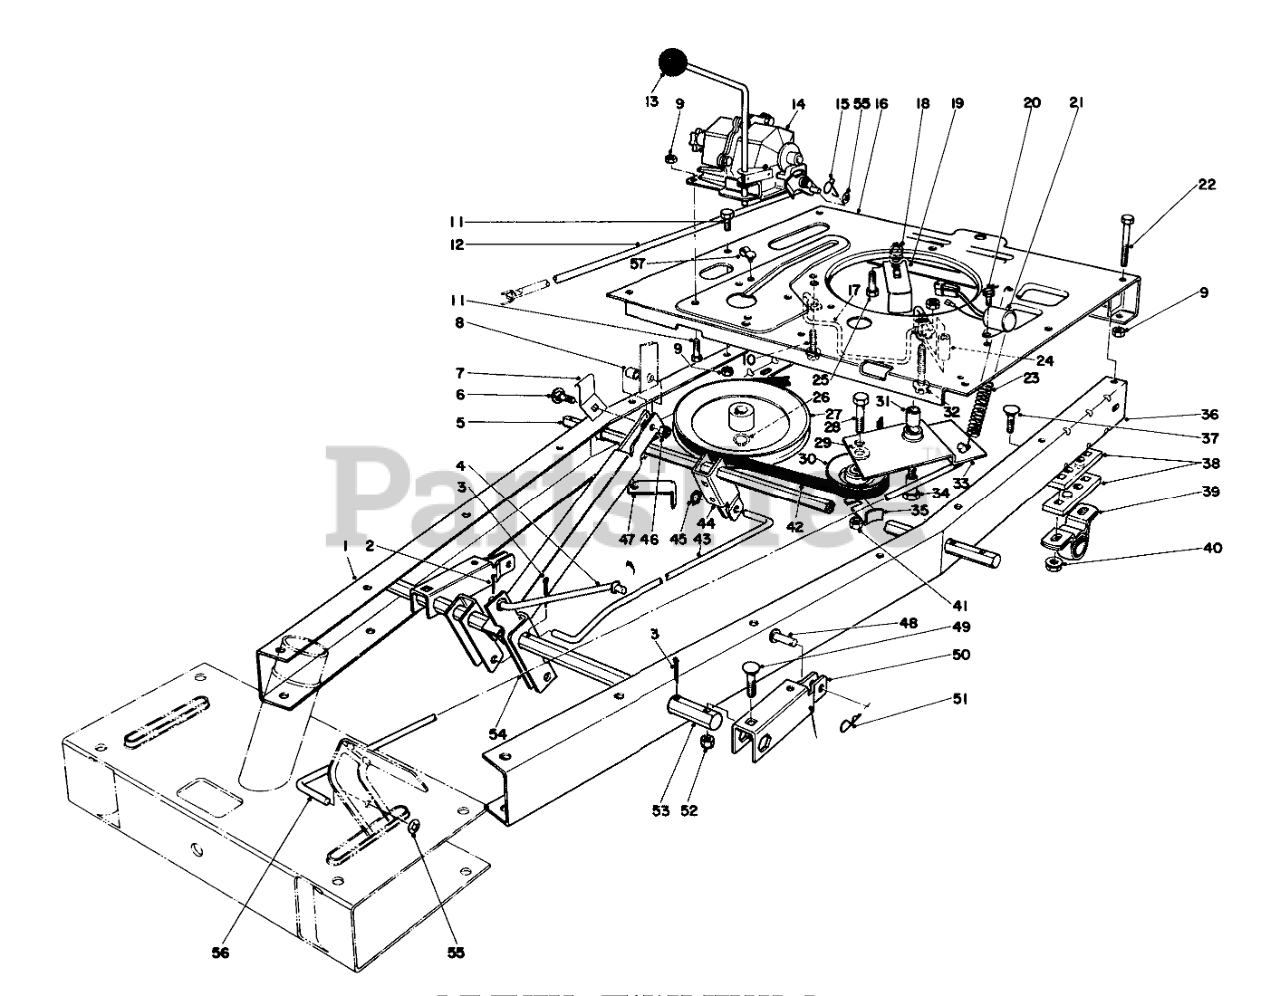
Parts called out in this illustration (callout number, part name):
1	Frame Channel R.H.
2	PIN-COTTER
3	PIN-COTTER
4	Deck Engagement Rod
5	Hex Shaft-Rear Lift
6	SCREW-CARR
7	Flat Spring
8	Spacer
9	NUT-LOCK, CONE
10	SCREW-HWHTF
11	SCREW-HH
12	Brake Rod
13	KNOB-CONTROL
14	Transmission
15	Brake Return Spring
16	Engine Mounting Plate
17	Engine Belt Guide
18	WASHER-PLAIN
19	Belt Retainer
20	10-16 X 3/8 THDG SCREW
21	Control Module
22	SCREW-HH
23	SPRING-EXTENSION
24	Spacer
25	Sems Screw
26	RING-SNAP, EXTERNAL
27	Pulley
28	SCREW-HH
29	Washer
30	PULLEY-IDLER
31	BUSHING
32	3/8-16 X 2-3/4 CAPSCR
33	Traction Idler (Incl. Ref. No.31)
34	CLUTCH PIVOT BOLT
35	RETAINER-BELT
36	Channel Frame L.H.
37	SCREW-CARR
38	Pillow Block Spacer
39	PILLOW BLOCK
40	NUT-HF
41	NUT-LOCK, CONE
42	TRACT DRIVE V-BELT
43	Lift Transfer Rod
44	Lift Arm Transfer
45	Grip Ring
46	NUT-HEX, SIDE DEFORM
47	TRANS BELT RET B
48	PIN-CLEVIS
49	SCREW-CARR
50	Deck Lift Arm
51	PIN-COTTER, HAIR
53	Front Lift
54	Arm Lever
55	PUSH ON SPEED NUT 1/4
56	Clutch Rod
57	Cable Holder
